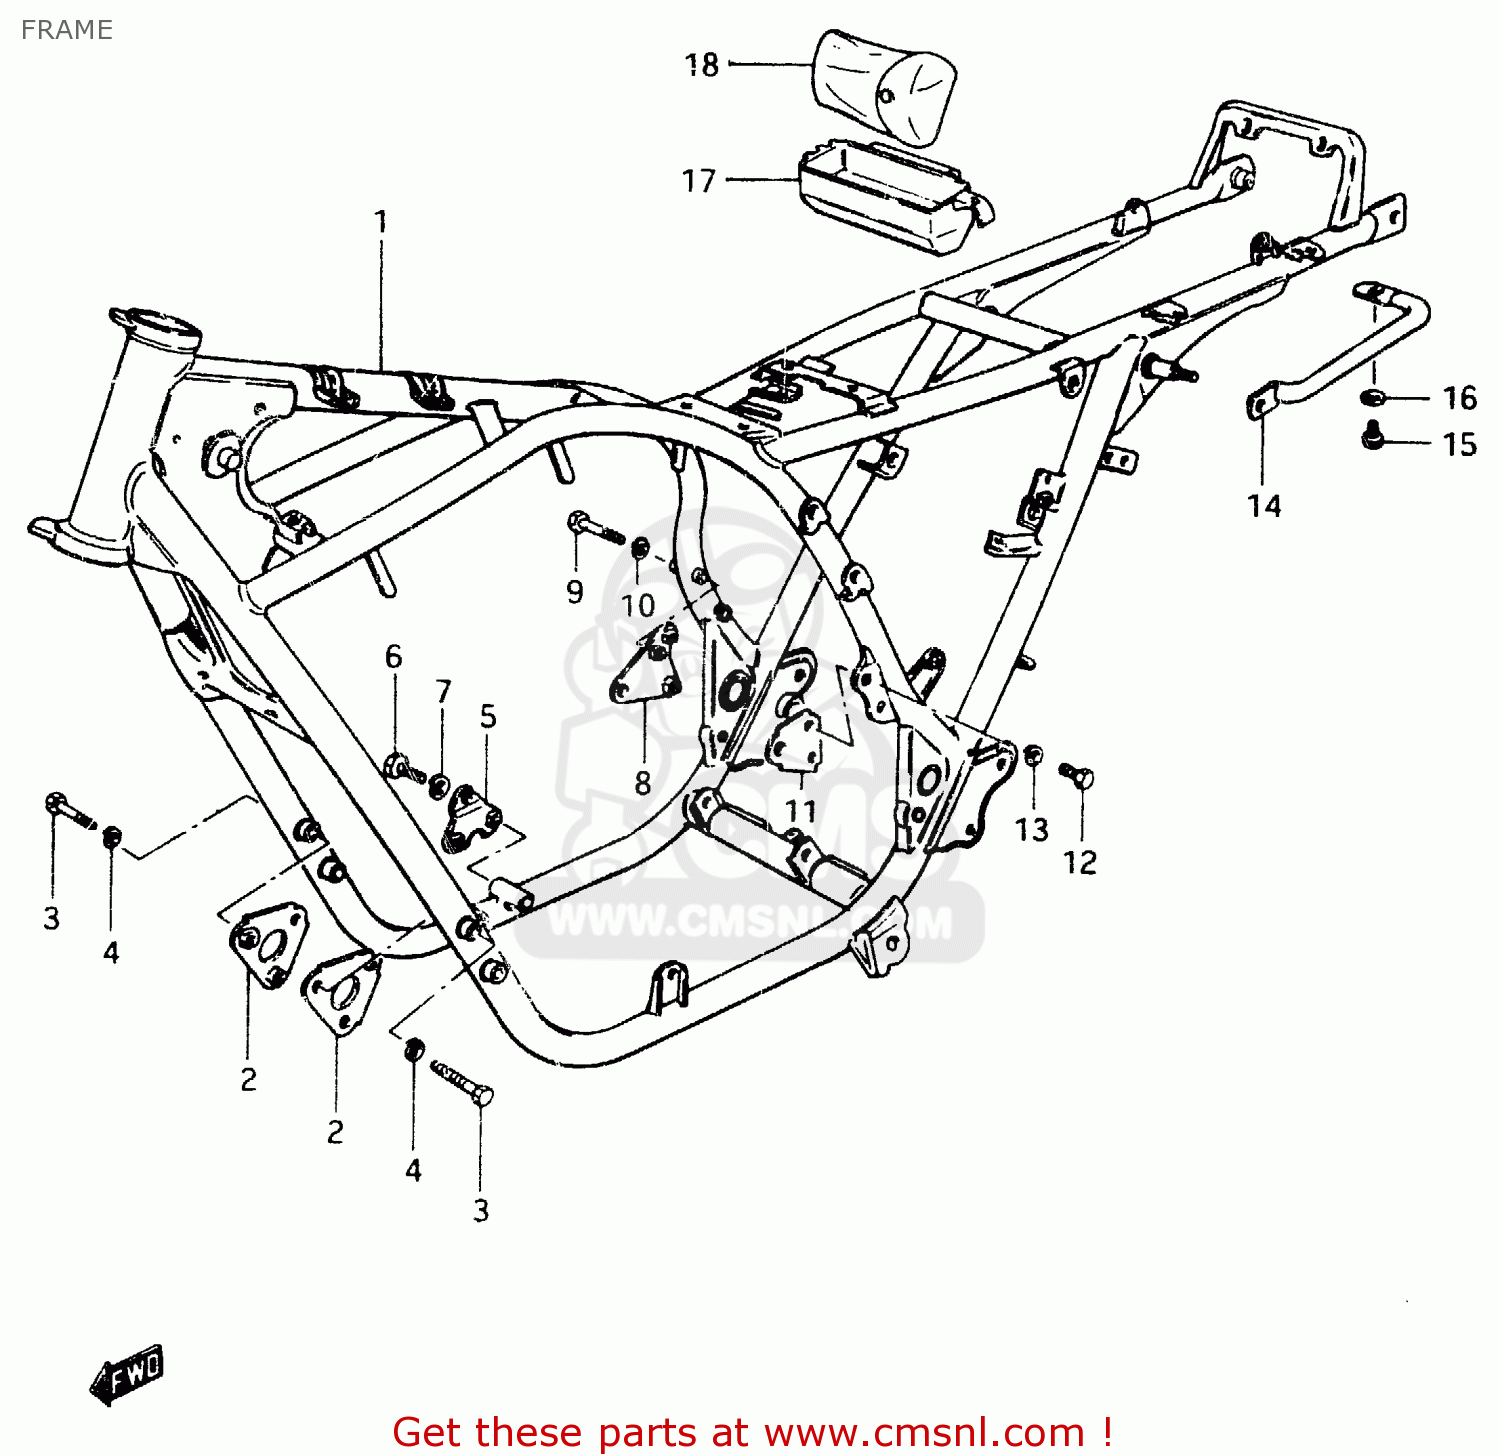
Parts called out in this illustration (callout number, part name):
1	FRAME (BLACK)
2	PLATE, NO. 1 (BLACK)
3	BOLT
4	LOCK WASHER
5	PLATE, NO. 2 RH (BLACK)
6	BOLT 8X50
7	LOCK WASHER
8	PLATE, NO. 4 RH (BLACK)
9	BOLT
10	LOCK WASHER
11	PLATE, NO.4 LH (BLACK)
12	BOLT
13	LOCK WASHER
14	GRIP, FRAME HANDLE
15	BOLT
16	WASHER
17	HOLDER, TOOL
18	TOOL SET
